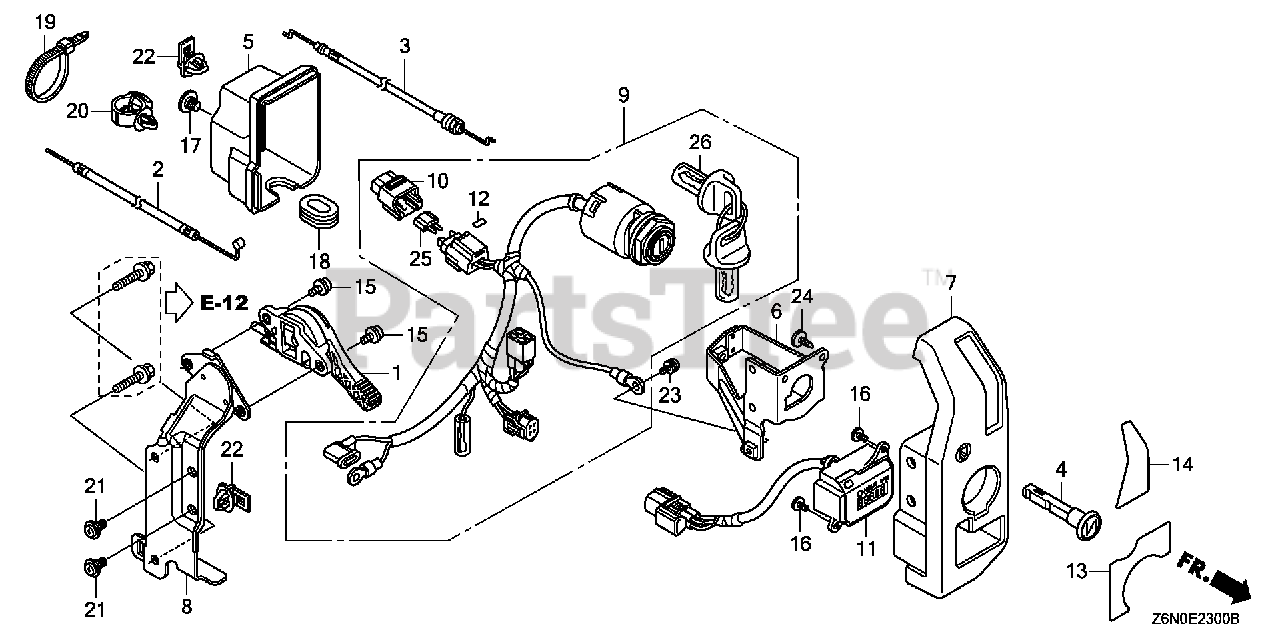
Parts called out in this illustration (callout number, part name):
1	LEVER ASSY., THROTTLE
2	CABLE, THROTTLE
3	CABLE, CHOKE
4	KNOB, CHOKE
5	COVER, CONTROL
6	BRACKET, SWITCH BOX
7	PANEL, CONTROL
8	BRACKET, CONTROL BOX
9	SWITCH ASSY., COMBINATION
10	COVER ASSY., FUSE
11	METER ASSY., HOUR
12	LABEL, FUSE (30A)
13	MARK, ENGINE SWITCH
14	MARK, THROTTLE SWITCH
15	BOLT, SOCKET (5X9)
16	SCREW, TAPPING (3X8) (PO)
17	SCREW, SPECIAL (6X8)
18	GROMMET, CONTROL BOX
19	BAND, WIRE (95MM)
20	CLIP, WIRE HARNESS
21	SCREW, PAN (5X10.5)
22	CLIP, CONNECTOR (BLACK)
23	SCREW-WASHER (5X8)
24	SCREW, TAPPING (5X14) (PO)
25	FUSE, MINI (30A)
26	KEY ASSY., COMBINATION SWITCH (W05)
